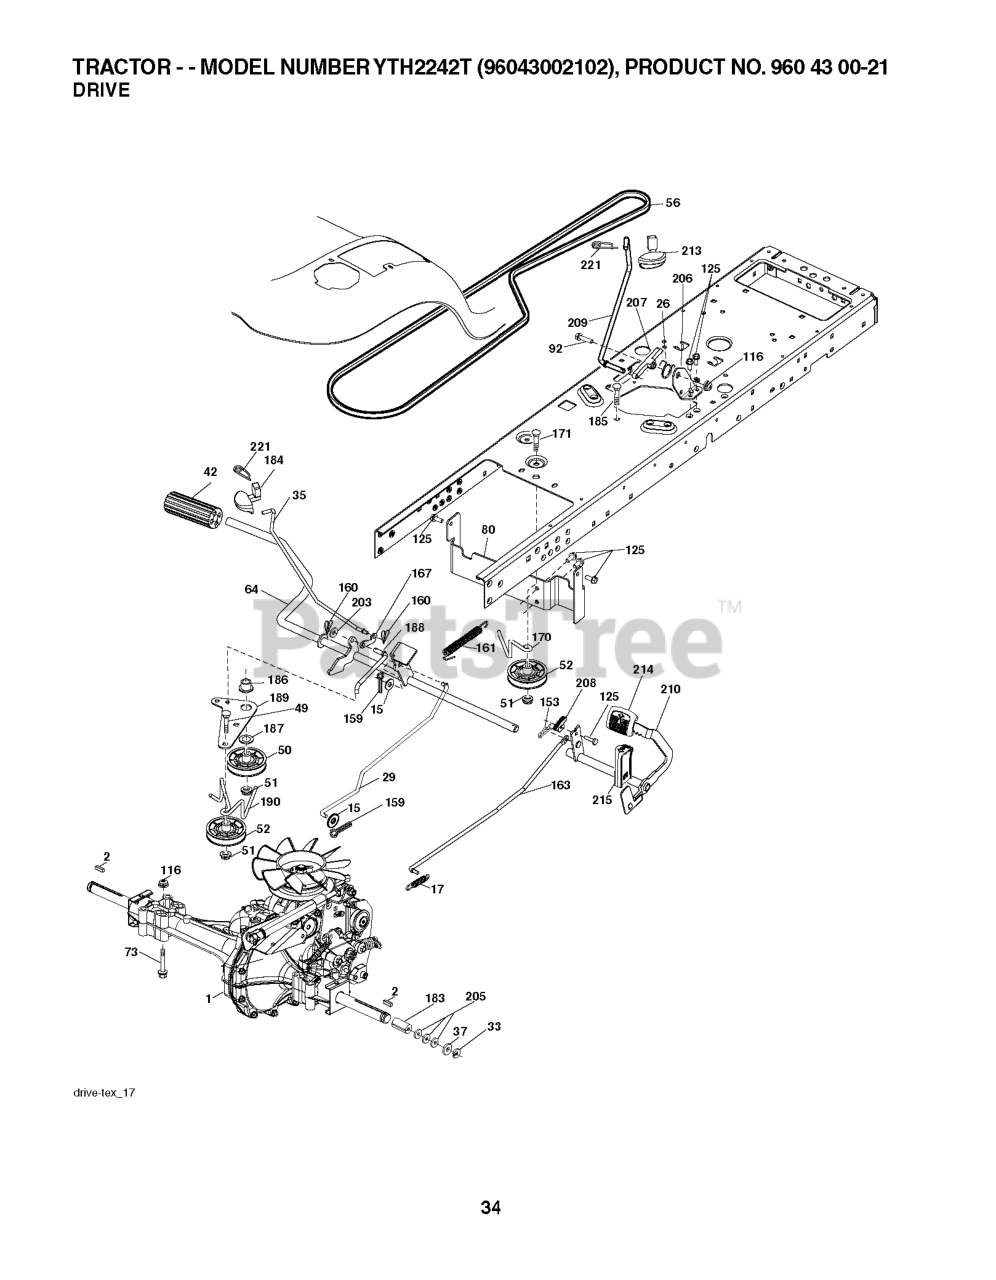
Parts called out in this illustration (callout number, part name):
2	SQUARE KEY
15	WASHER
17	SPRING.BRAKE.HG3000/3500
26	SPRING.RETURN.CRUISE
29	ROD.BRAKE.HG-0510
35	ROD.BRAKE.PARKING.GT.H
42	PEDAL COVER T
50	IDLER.FLAT.910.OFFSET
51	NUT LOCK FLG 3/8-16 UNC
52	IDLER.V-GROOVE.910.OFFSET
73	BOLT HEX 5/16-18 GR 5
80	BRKT.STRP.TRQ.LT.HYD.C
92	BOLT
116	NUT LOCK HEX FLANGE 5/16-18
125	SCREW
153	RETAINER M
159	COTTER PIN
160	RETAINER CLIP
161	SPRING.RETURN.CLUTCH.2006
163	ROD.PEDAL.CONTROL.0510
167	LATCH.BRAKE.SPRING
170	KEEPER.V-IDLER.CENTER.
183	SPACER AXLE
184	HANDLE.PARKG.BRK.HUSQ X667
186	SPACER.RETAINER
187	WASHER 12/32X2X10GA
188	RP.LINK.CLUTCH.GROUND.DRIVE
189	BELLCRANK.GROUND.DRIVE.TEX.
190	KEEPER.BELLCRANK.DRIVE
196	SCREW 3/8-16X1
197	LINK.CLUTCH.ANIT-ROTAT
203	WASHER
206	BRKT.MOUNT.LATCH.CRUIS
207	LATCH.CONTROL.CRUISE
208	GEAR.SECTOR.CONTROL.CR
209	ROD.CONTROL.CRUISE.GT.
210	ROCKER.ASM.PEDAL.CONTR
213	KNOB.CONTROL.CRUSIE.HU
214	PEDAL.FORWARD.TEX.GT.4
215	PEDAL.REVERSE.TEX.GT.4
221	RETAINER.SPRING.CLIP.H
